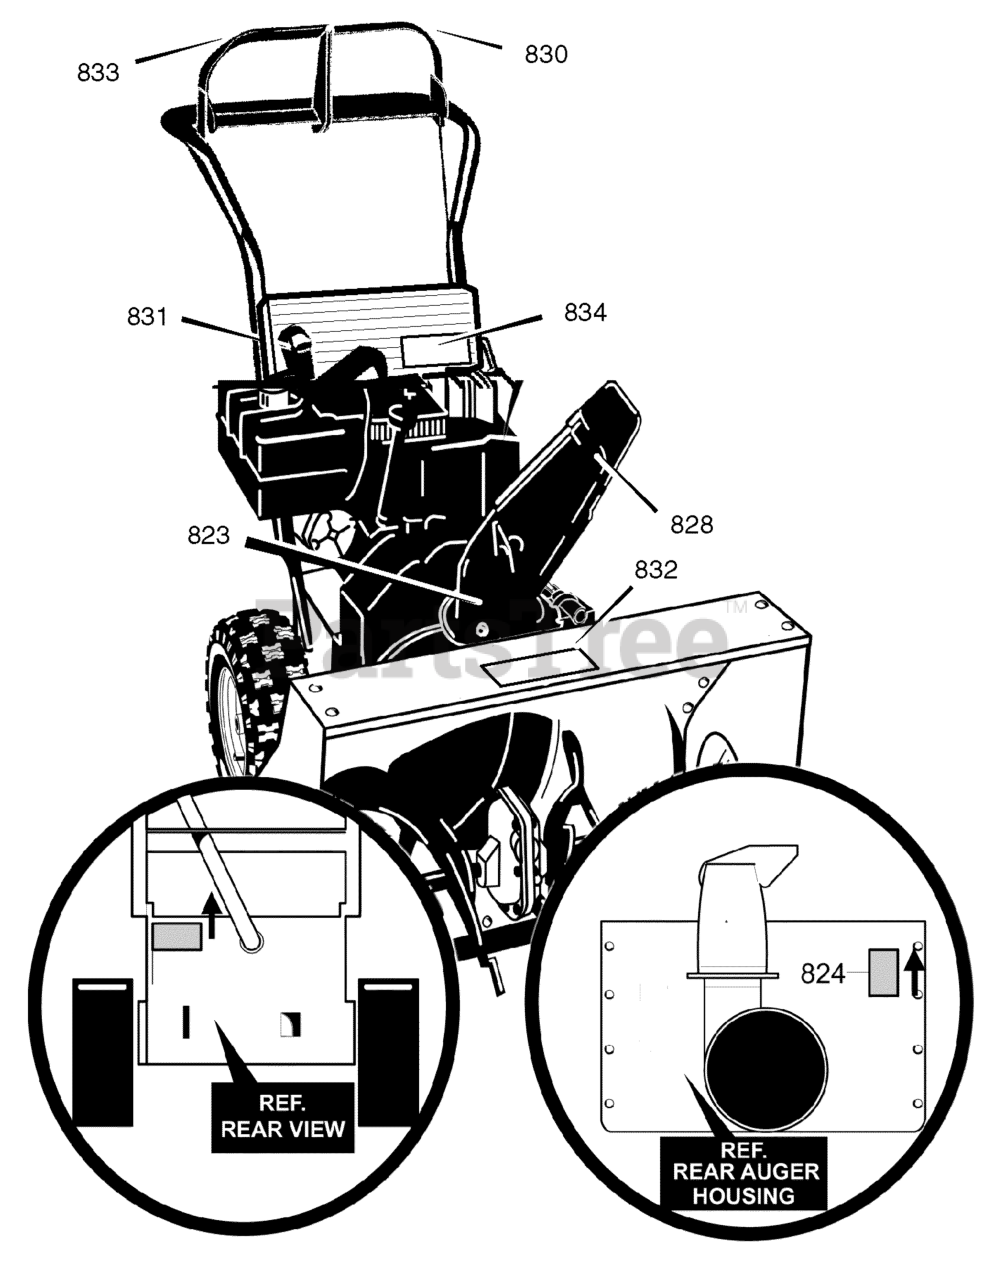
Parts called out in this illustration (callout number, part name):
823	DECAL, DANGER CHUTE HAND
824	DECAL, DANGER FOOT
828	DECAL, THROWN OBJECTS
830	DECAL, TRACTION DRIVE
831	DECAL, GEAR SELECTOR
832	DECAL, MURRAY 5/22
833	DECAL, AUGER DRIVE
834	DECAL, MILLER HIGH LITE
